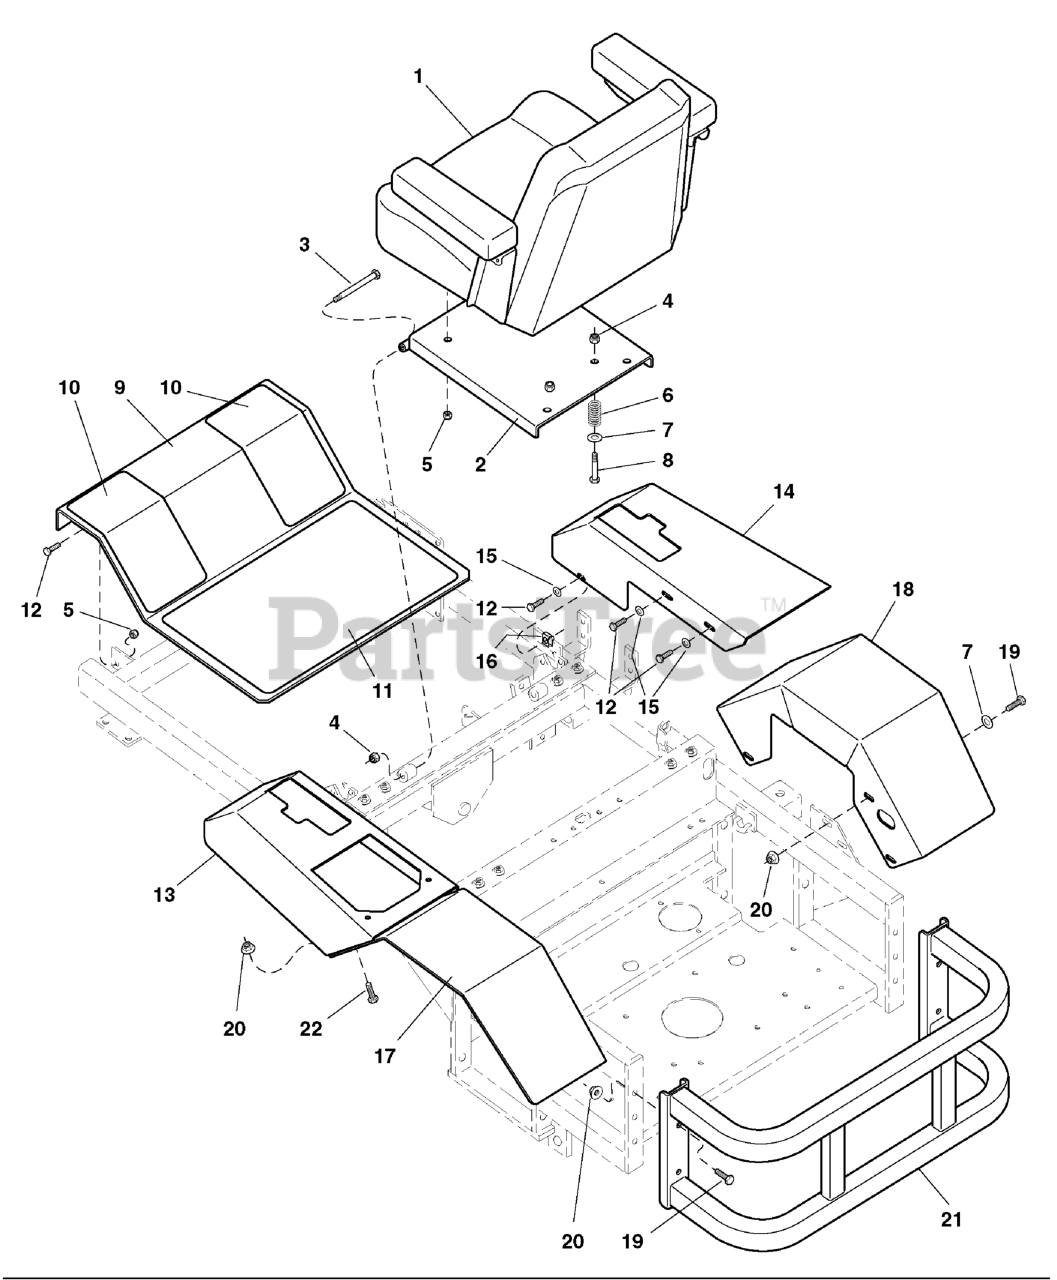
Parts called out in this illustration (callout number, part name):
1	SEAT, GRAY, NO LOGO, CMPT
1	CUSHION, Seat, Gray
1	CUSHION, BACK
1	ARM REST, Black
2	SEAT MOUNT PLATE
3	BOLT, 3/8-16 X 4" GD5 CZ
4	NUT, 3/8-16 HEX NYLON LOCK
5	NUT, 5/16-18 Hex Nylon Lock
6	SPRING, Compression
7	WASHER, 3/8 SAE
8	BOLT, 3/8-16 X 2-1/4" GD5 CZ
9	FLOOR PAN
10	SAFETY WALK
11	SAFETY WALK, 11.50 X 19.00
12	BOLT, 5/16-18 X 1 GD5 YZ
13	COVER, Control - LH
14	COVER, Control - RH
15	WASHER, 5/16" SAE
16	BODY CLIP, 5/16-18-7GA MATERIAL
17	FENDER, LH
18	FENDER, RH
19	BOLT, 3/8-16 X 1" GD5 CZ
20	NUT, 3/8-16 Hex Serrated Flange
22	BOLT, 3/8-16 X 3/4" GD5 CZ
23	SPRING, EXTENSION, SEAT ADJUSTMENT (YEL OR BLK)
